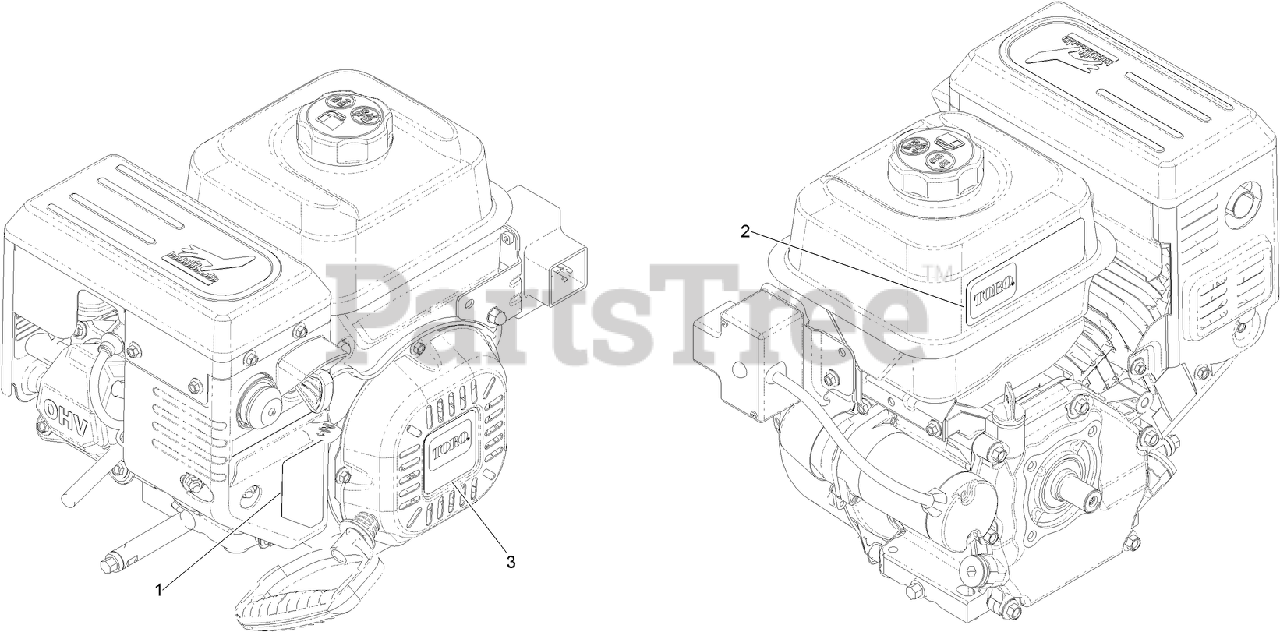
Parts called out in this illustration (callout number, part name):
1	DECAL-CONTROL, ENGINE
2	DECAL-ENGINE SERIES, G250
3	DECAL-RECOIL, G250
